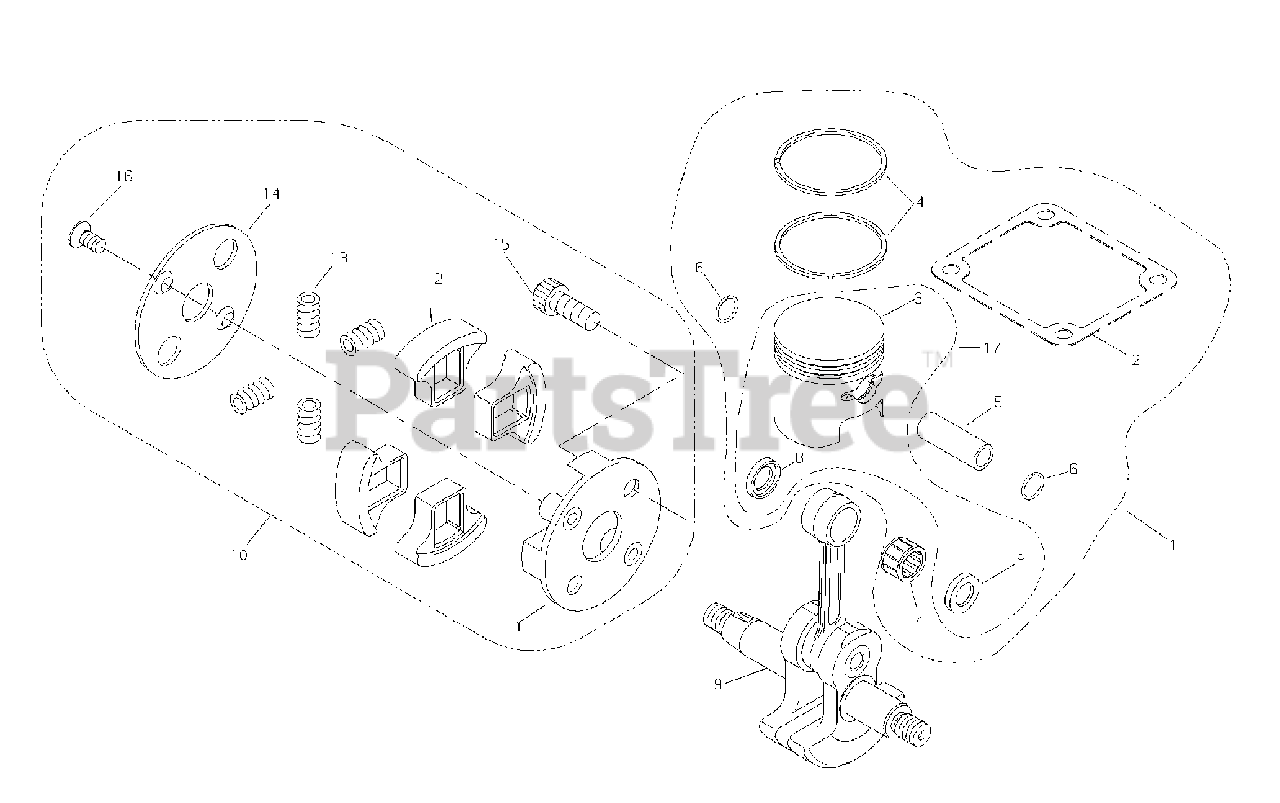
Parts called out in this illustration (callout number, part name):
1	PISTON KIT
2	GASKET, CYLINDER
3	PISTON
4	RING, PISTON
5	PIN, PISTON 10
6	RING, SNAP
7	BEARING, NEEDLE 10
8	SPACER, PISTON
9	CRANKSHAFT ASSY
10	CLUTCH ASSY
11	BOSS, CLUTCH
12	SHOE, CLUTCH
13	SPRING, CLUTCH
14	PLATE, CLUTCH
15	BOLT, CLUTCH
16	BOLT 5
17	PISTON SET
